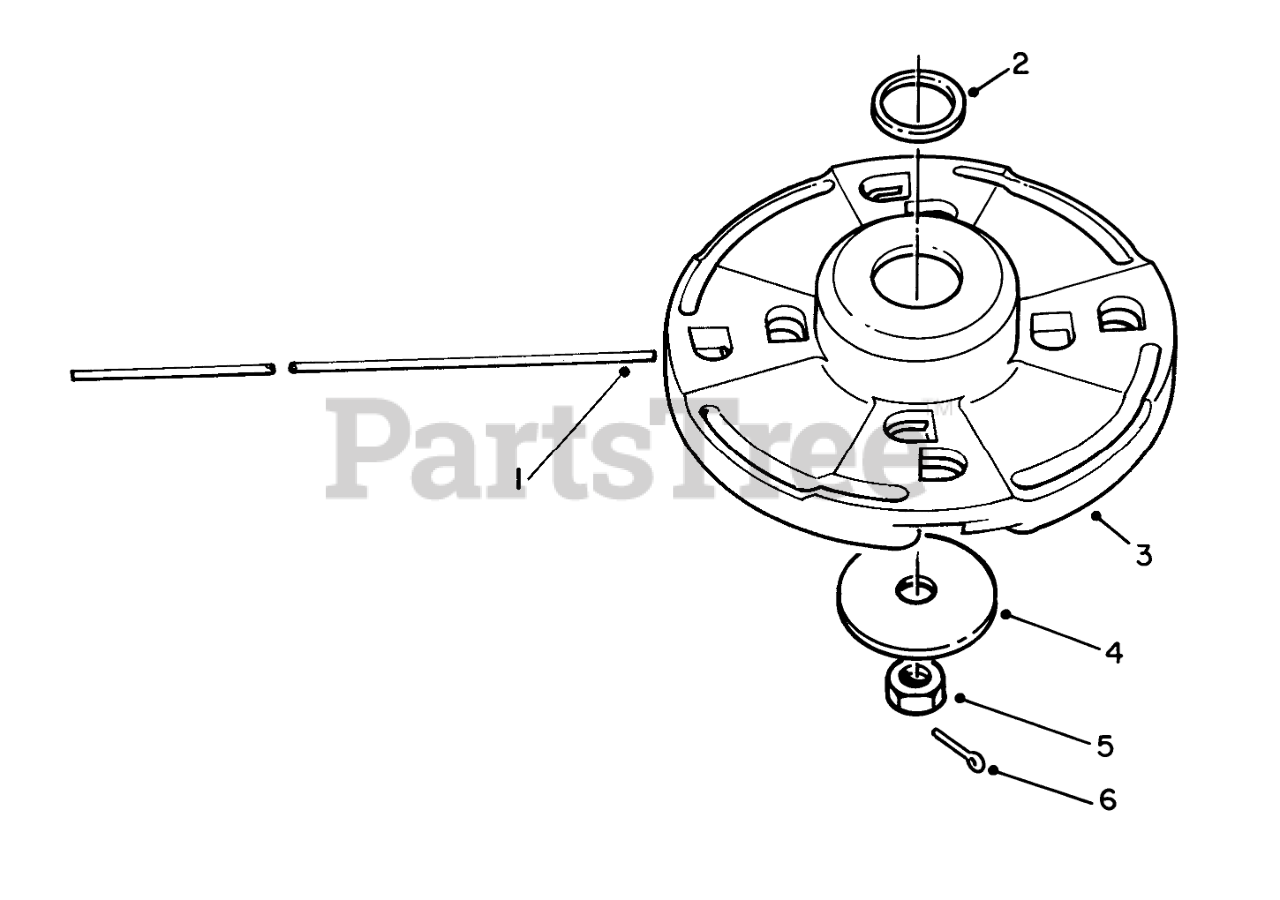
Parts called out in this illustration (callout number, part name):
1	LINE PACK (100)
3	Head Assembly (Incl. Ref. #2)
4	WASHER
6	1/16 X 1 LG COTTER PIN
